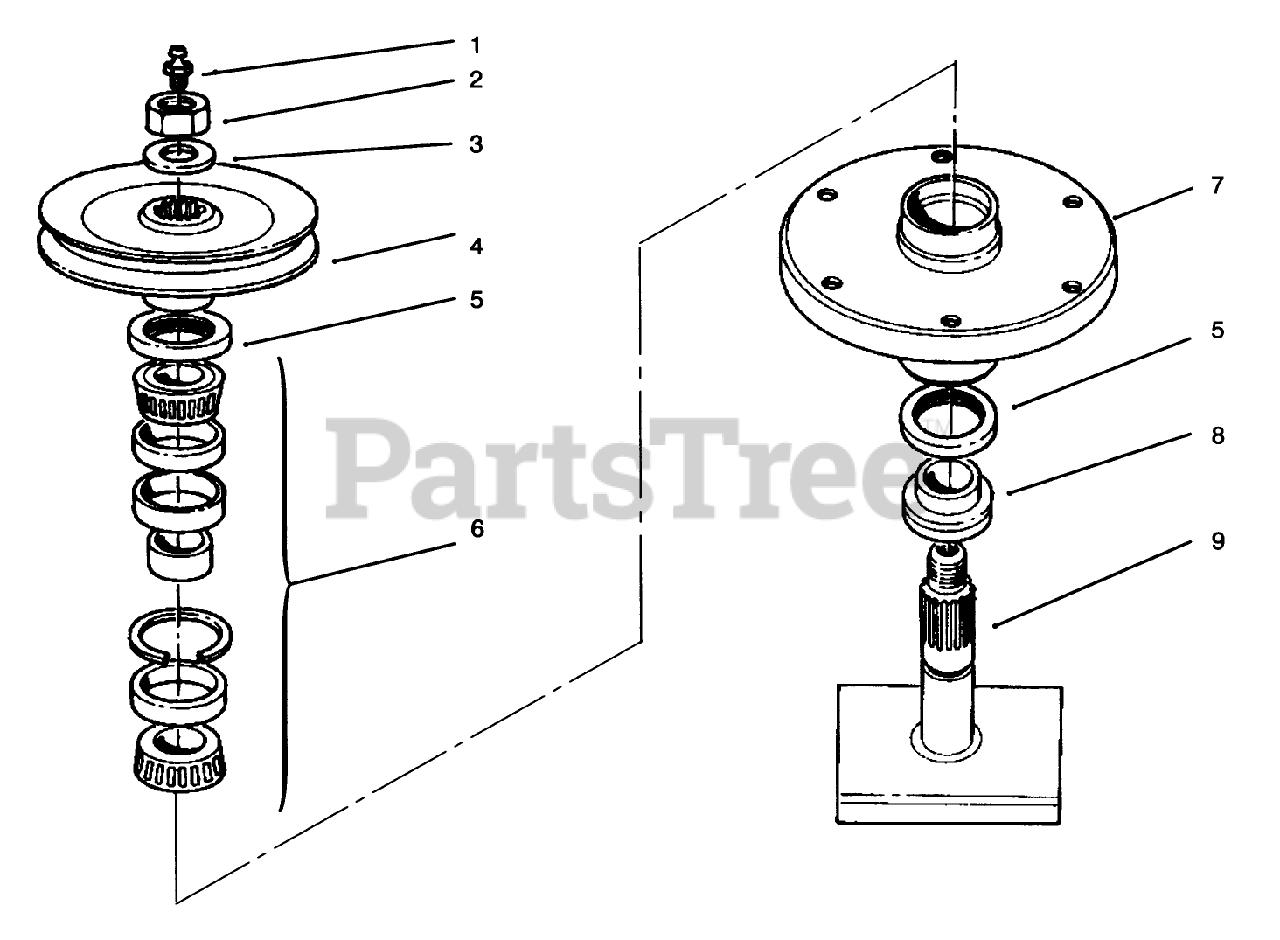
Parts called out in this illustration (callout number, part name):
1	FITTING-GREASE
2	NUT-HEX
3	WASHER
4	PULLEY AND HUB ASM
5	SEAL-OIL
6	BEARING ASM
7	HOUSING-SPINDLE
8	SPACER
9	SHAFT
